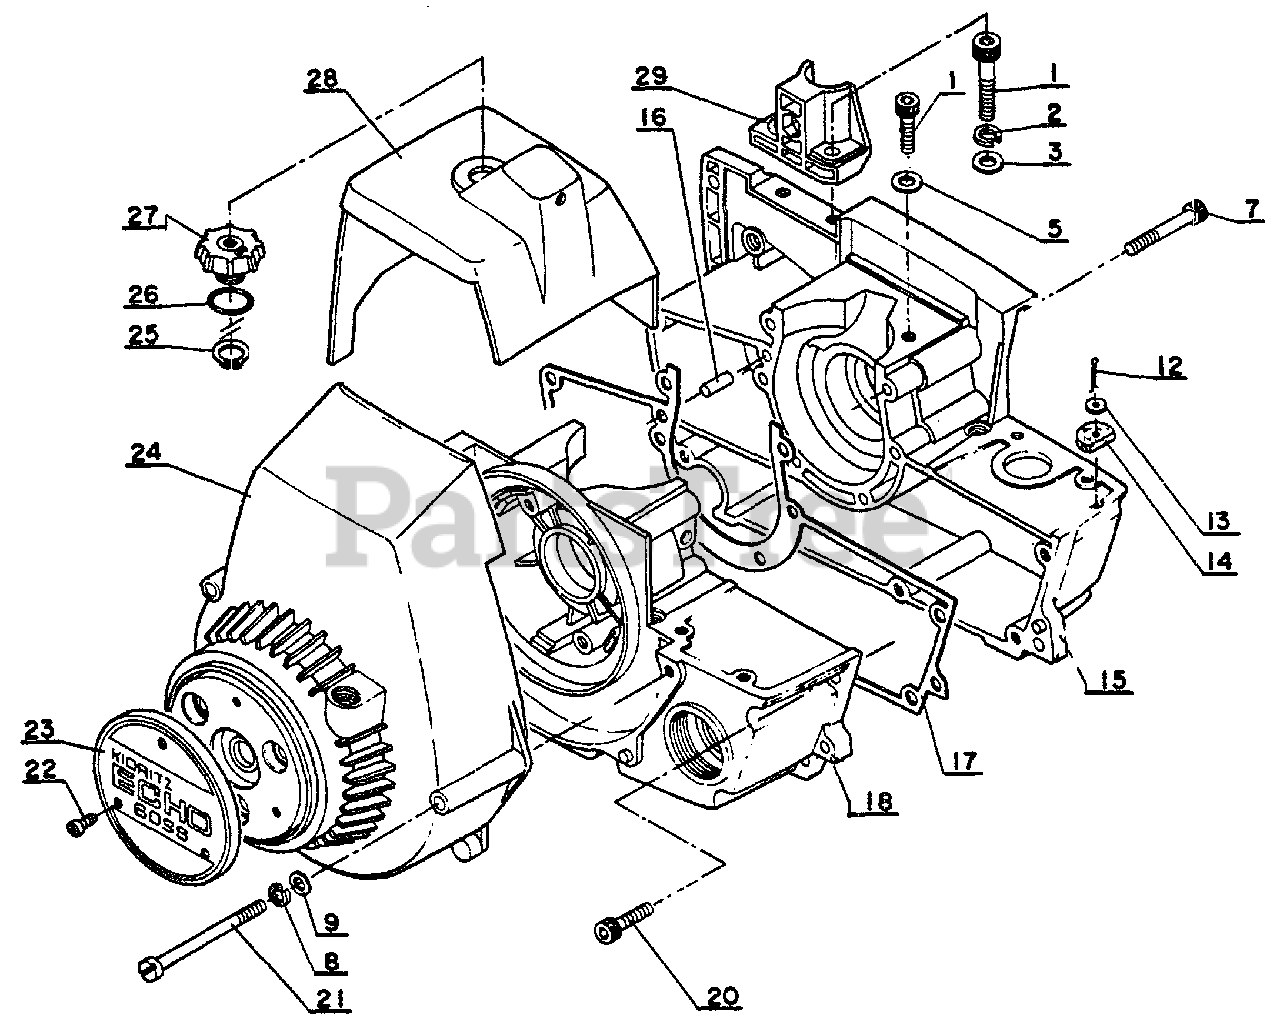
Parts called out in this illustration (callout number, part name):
1	SCREW - 6X25
2	LOCKWASHER - 6
3	WASHER - 6
7	SCREW - 5X35
8	LOCKWASHER - 5
9	WASHER - 5
12	PIN, SPLIT -- 2X15
13	WASHER - 2
14	SEAL, FELT
15	CRANKCASE
16	PIN - LOCATING
17	GASKET, CRANKCASE
20	SCREW - 5X20
22	SCREW - 3X6
23	Nameplate
24	CASE, STARTER
25	RING, RETAINING - 11
26	O-RING - 14
28	COVER, ENGINE
29	BRACKET, HANDLE
